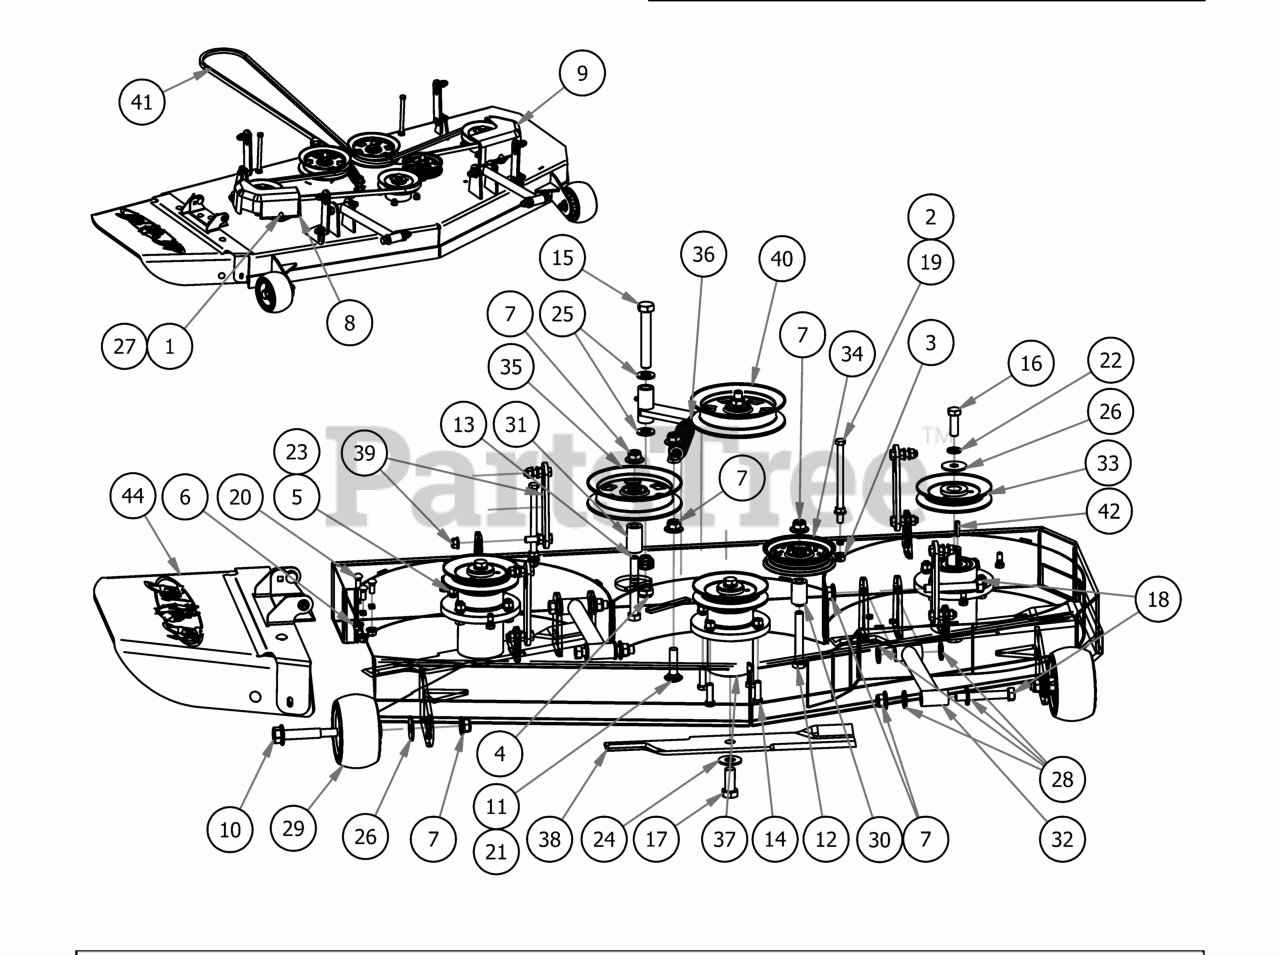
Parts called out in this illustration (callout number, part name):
1	Acorn nut-pulley Cover
2	3/8" Flange Nut
3	3/8" Nylock Flange Nut
4	5/8" Nylock (1/2 Jam)
5	3/8" Hex Nut
6	5/16" Nylon Flange Nut
7	1/2-13 Nylon Flange Nut
8	pulley cover chute side
9	pulley cover non-chute side
10	Deck Wheel Bolt
11	1/2 x 2" Carriage Bolt
12	1/2 x 3 1/2 Flange Bolt Grade 8
13	1/2" x 4" Bolt (Grade 8)
14	3/8" x 1 1/4" Hex Bolt
15	5/8" x 4" Hex Bolt
16	1/2"-20 x 1 1/2 - Grade 5 Fine Thread Bolt
17	5/8 x 1 1/2 Grade 8 Hex Bolt (Fine)
18	1/2-13 x 3 1/2 GR 5 Hex Bolt
19	3/8-16 x 5 1/2 Hex Bolt
20	5/16-18x3/4 carriage bolt
21	.517 Square Hole Round Washer
22	1/2" Lock Washer
23	3/8" Lock Washer
24	5/8'' Flat Washer
25	.630 ID Plastic Washer
26	1/2" Belleville Washer
27	.360 ID Plastic Washer-Black
28	.505 Nylon Spacer
29	Deck Wheel
30	.502 ID X .750 OD X 1.500 Long Spacer
31	1 3/4" Pulley Spacer
32	MZ/ZT Deck Locator
33	MZ Deck Pulley
34	4-3/4 Idler Pulley
35	5-3/4 Idler Pulley
36	Deck Idler Spring
37	Spindle Assembly-MZ
38	48" High Lift Fusion Blade
39	Deck Hanger Assembly
40	2017 54"/48" Deck Idler Assembly
41	B147 Deck Belt
42	3/16 x 1 Square Key
43	48" Welded Deck Shell
44	MZ Discharge Chute Assembly
